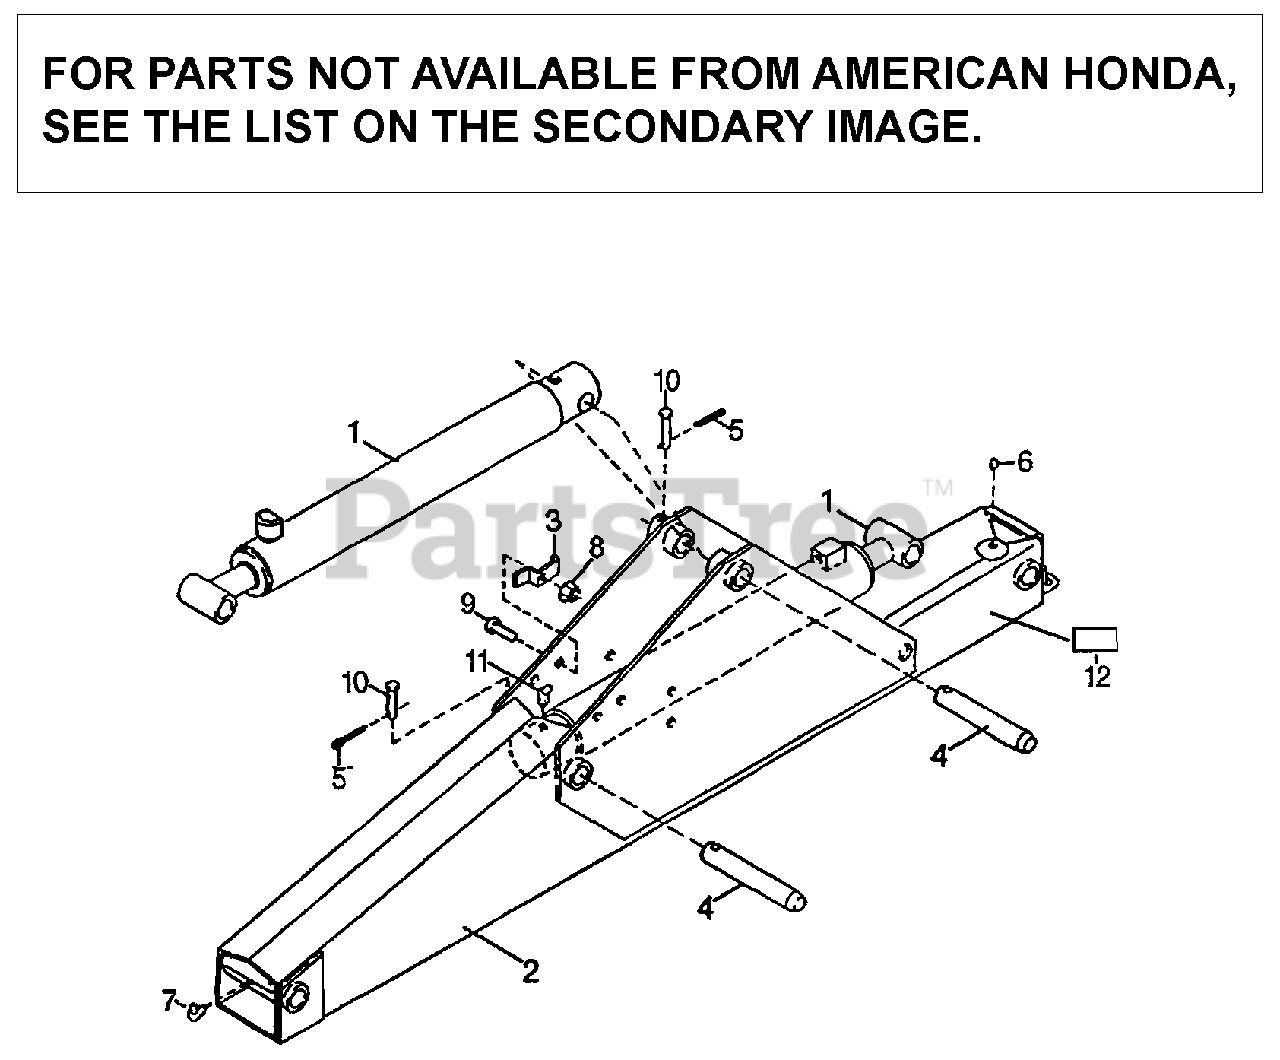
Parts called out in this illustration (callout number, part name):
1	CYLINDER, HYDRAULIC (2-1/2X16-3/4)
2	WELDMENT ASSY., BOOM
3	CLAMP, CYLINDER HOSE
4	PIN, PIVOT
12	DECAL, LOCK
